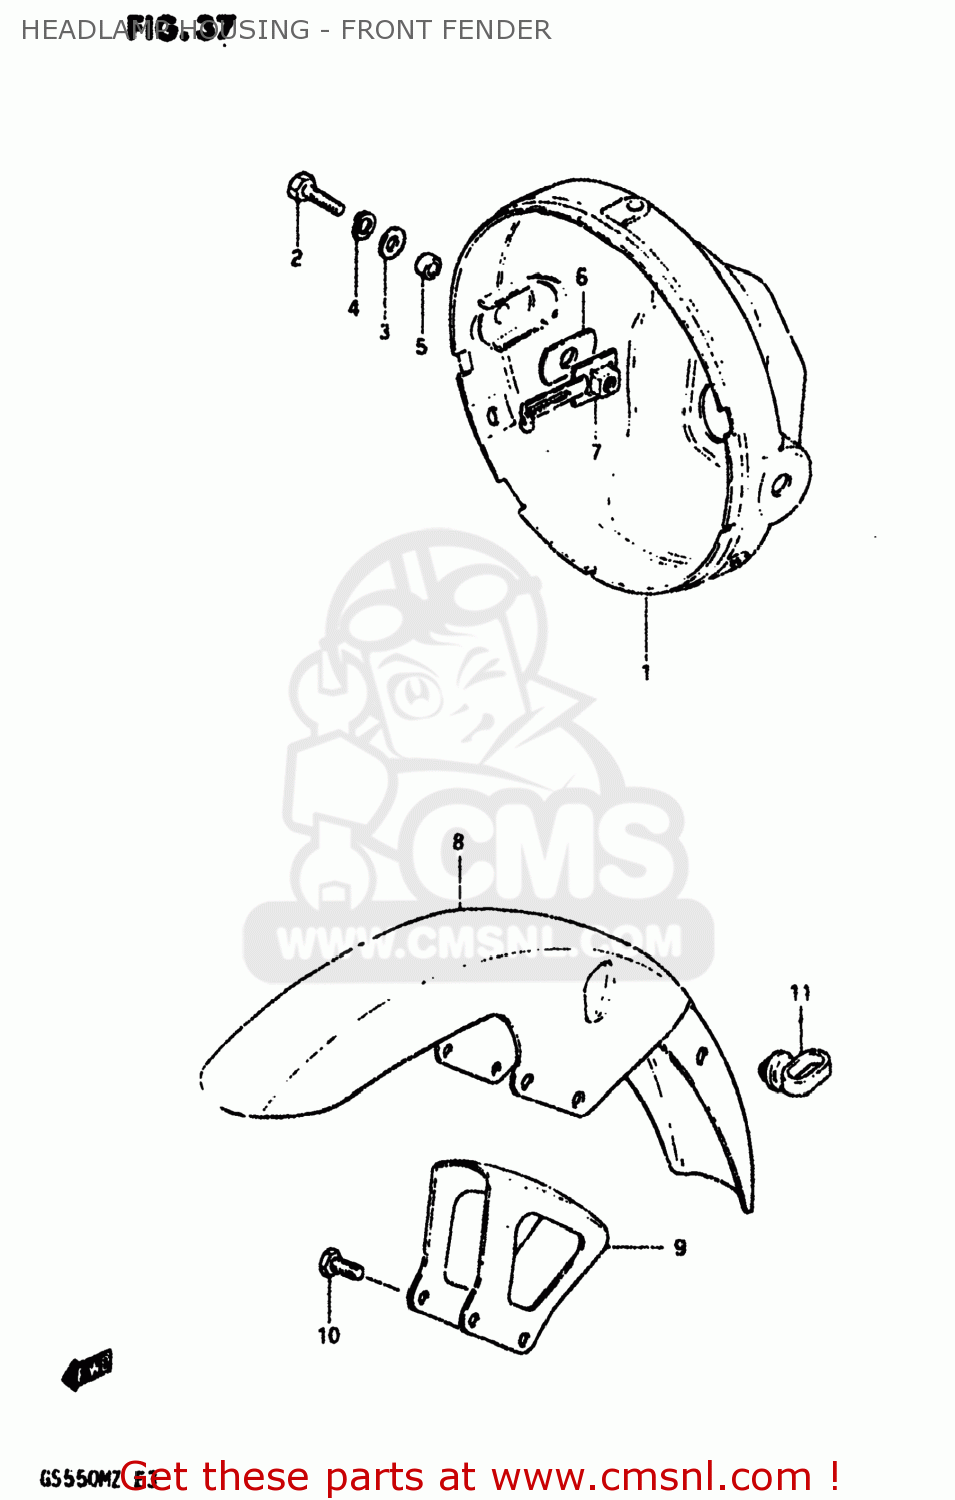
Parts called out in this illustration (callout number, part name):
1	HOUSING,HEADLAMP
2	BOLT
3	WASHER
4	LOCK WASHER
5	SPACER (8.8X12X7)
6	CUSHION
7	PLATE,HEADLAMP HOUSING
8	FENDER,FRONT
9	BRACE,FRONT FENDER
10	BOLT 8X16
11	GUIDE,CABLE
